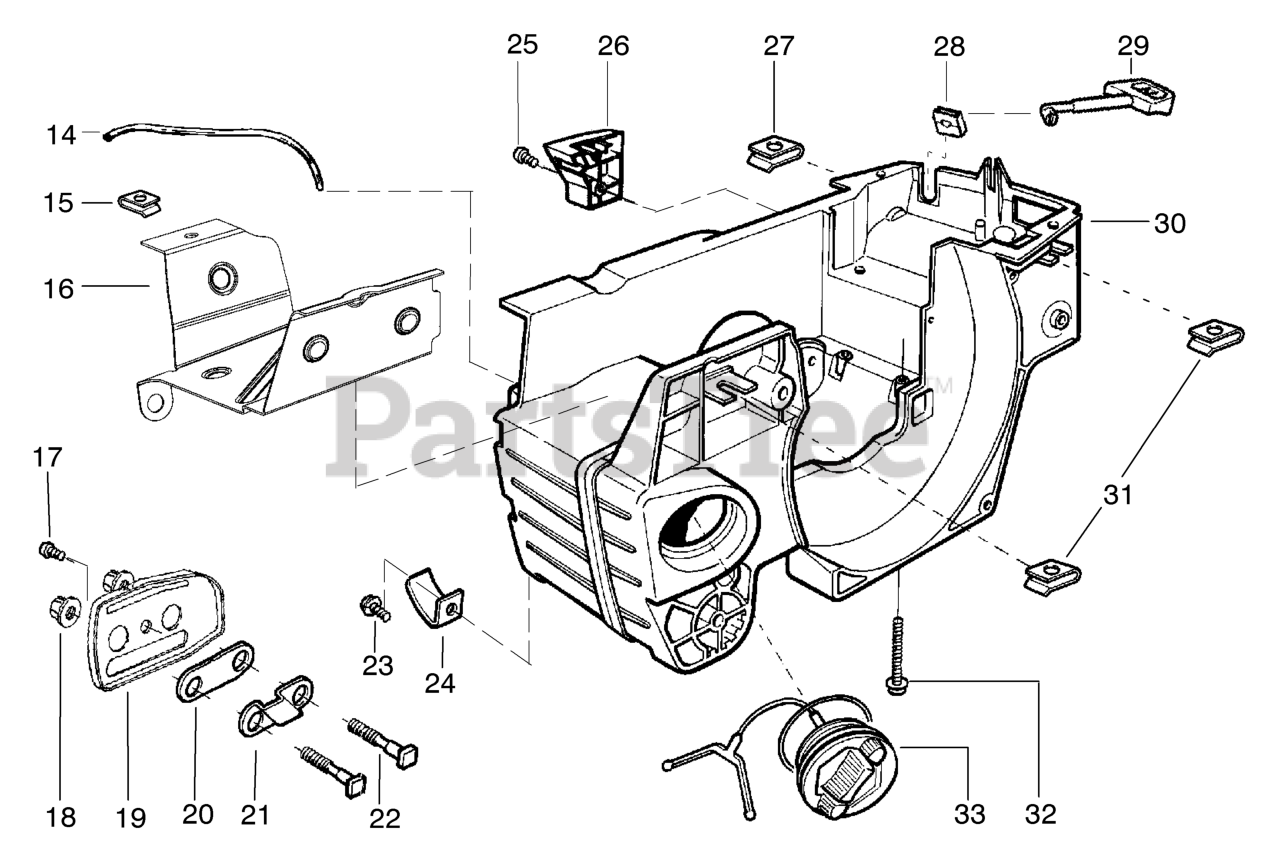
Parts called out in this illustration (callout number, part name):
14	TUBE
16	HEATSHIELD, LOWER
17	SCREW
20	OIL TANK GASKET
21	PLATE,BAR MOUNT
22	BAR BOLT 36/41
24	CHAIN CATCHER 36/41
26	LIMITER COVER
28	CHOKE GUIDE 36/41
29	CHOKE 36/41
30	KIT ASSY CHASSIS
32	SCREW M5-0.8X35M TAP
